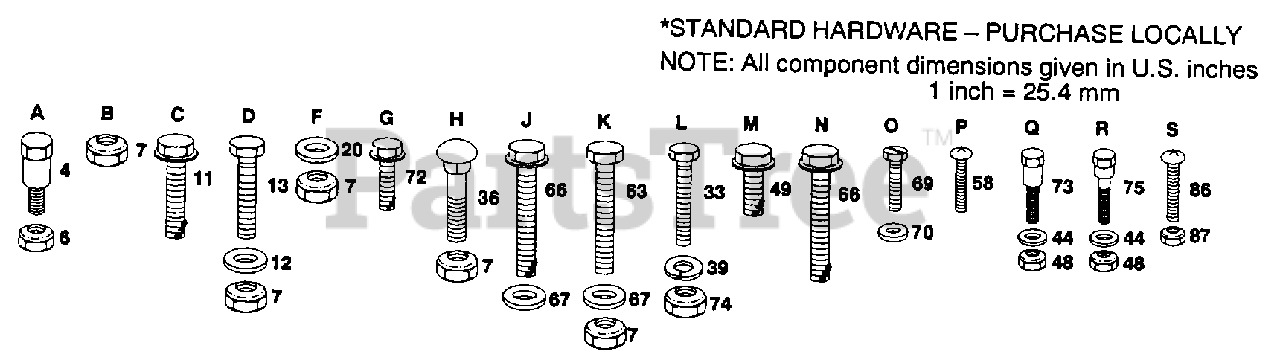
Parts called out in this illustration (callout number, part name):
11	SCREW
12	WASHER
20	WASHER
33	BOLT LT
36	BOLT
39	LOCKWASHER
49	SCREW LT
63	BOLT
66	SCREW GTV
67	WASHER HYT
69	SCREW
73	BOLT T
75	"BOLT,SHOULDER"
78	BOLT
87	"NUT,KEPS"
